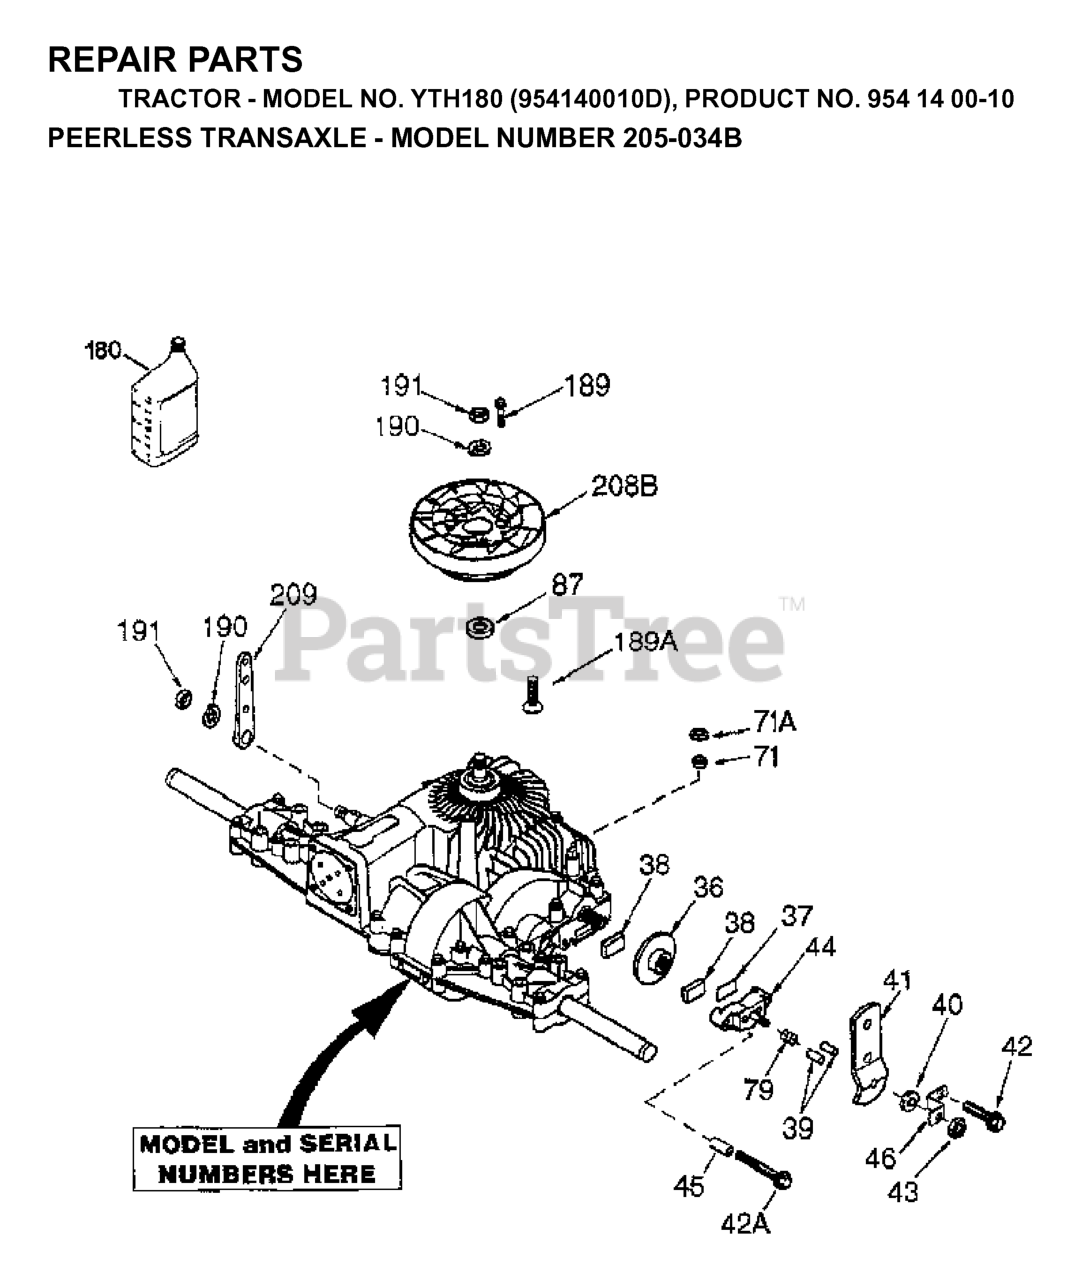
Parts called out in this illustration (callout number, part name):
36	Brake Disk
37	Plate, Brake pad
38	Brake Pad (pkg of 2)
39	Pin, Dowel
40	Washer, Flat
42	Screw, Flanged Hex Head, Thread Forming 1/4-20 x 1-1/4
42A	Screw, 1 /4-20 x 2-1 /4"
43	Lock Nut 5/16-24
44	Holder, Brake pad
45	Spacer (1/2" OD)
71	Seal, Square Cut
79	Piston Assembly
180	Gear Oil 80W90
